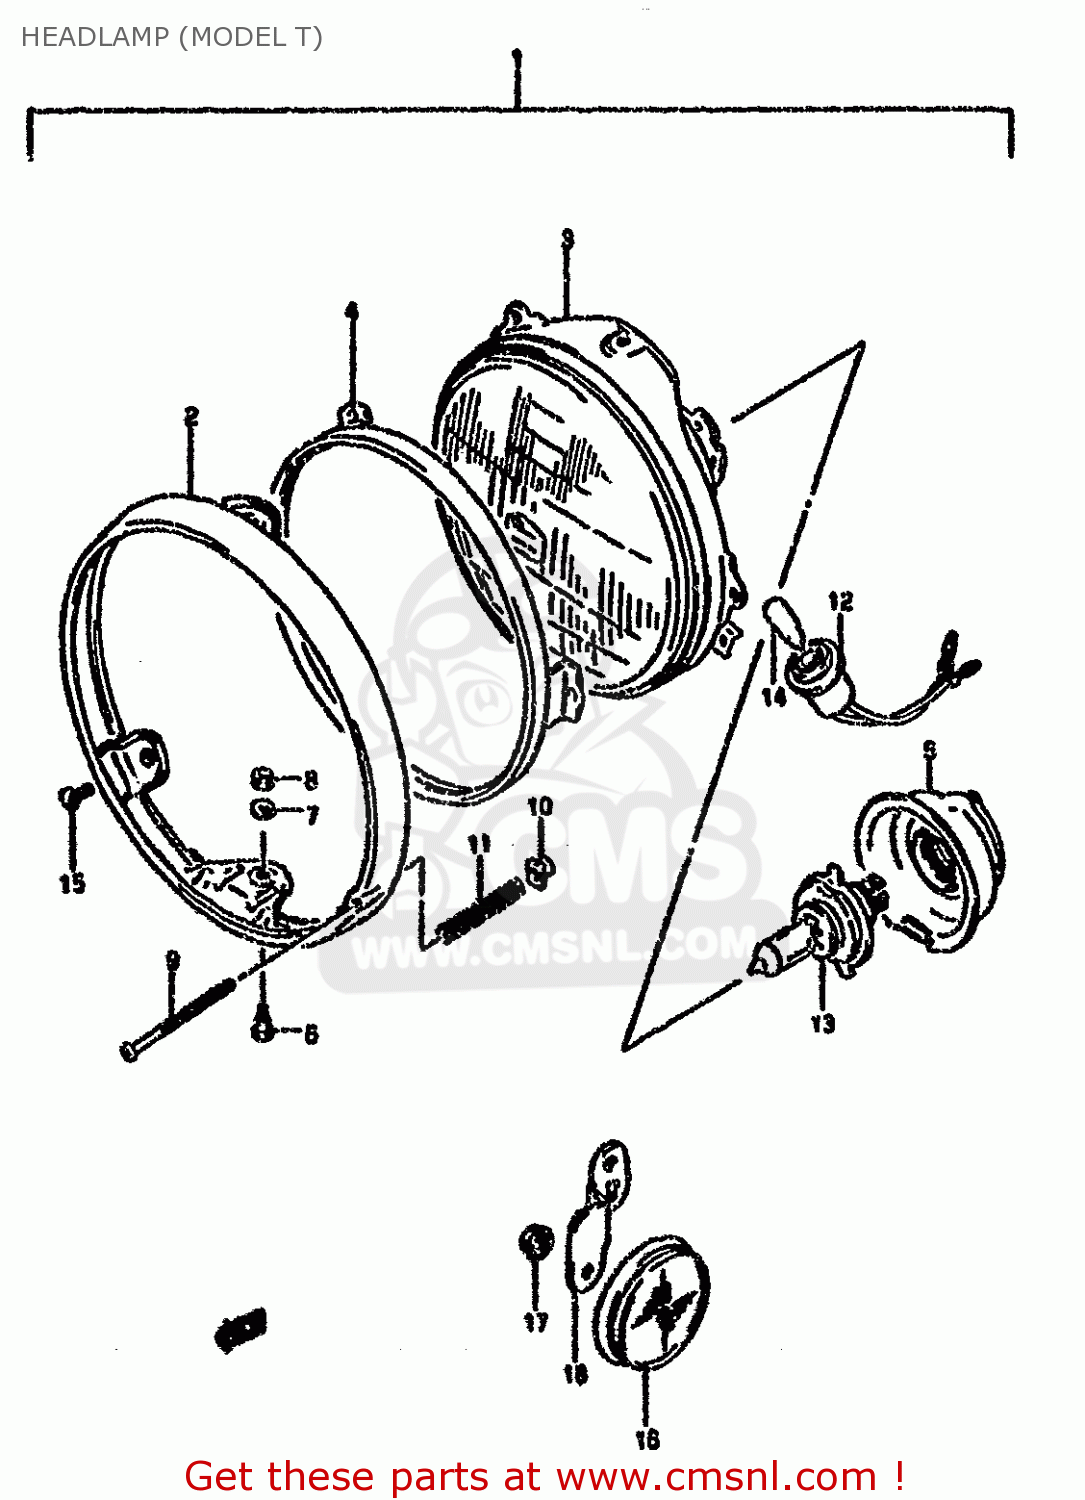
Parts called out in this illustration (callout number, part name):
1	HEADLAMP ASSY
2	RIM,HEADLAMP
3	LAMP UNIT
4	RING
5	COVER,SOCKET
6	H/LAMP LENS UNIT FITING SCRE
7	WASHER,LOCK
8	NUT
9	SCREW
10	NUT
11	SPRING,ADJUSTING
12	SOCKET,PARKING LAMP
13	BULB(12V60/55W,H4)
14	BULB(12V4W)
15	SCREW
16	REFLECTOR,REFLEX FR
17	NUT
18	BRACKET,SIDE REFLECTOR
22	SCREW
23	REFLECTOR,REFLEX FR
24	NUT
25	BRACKET,FRONT SIDE,REAR
